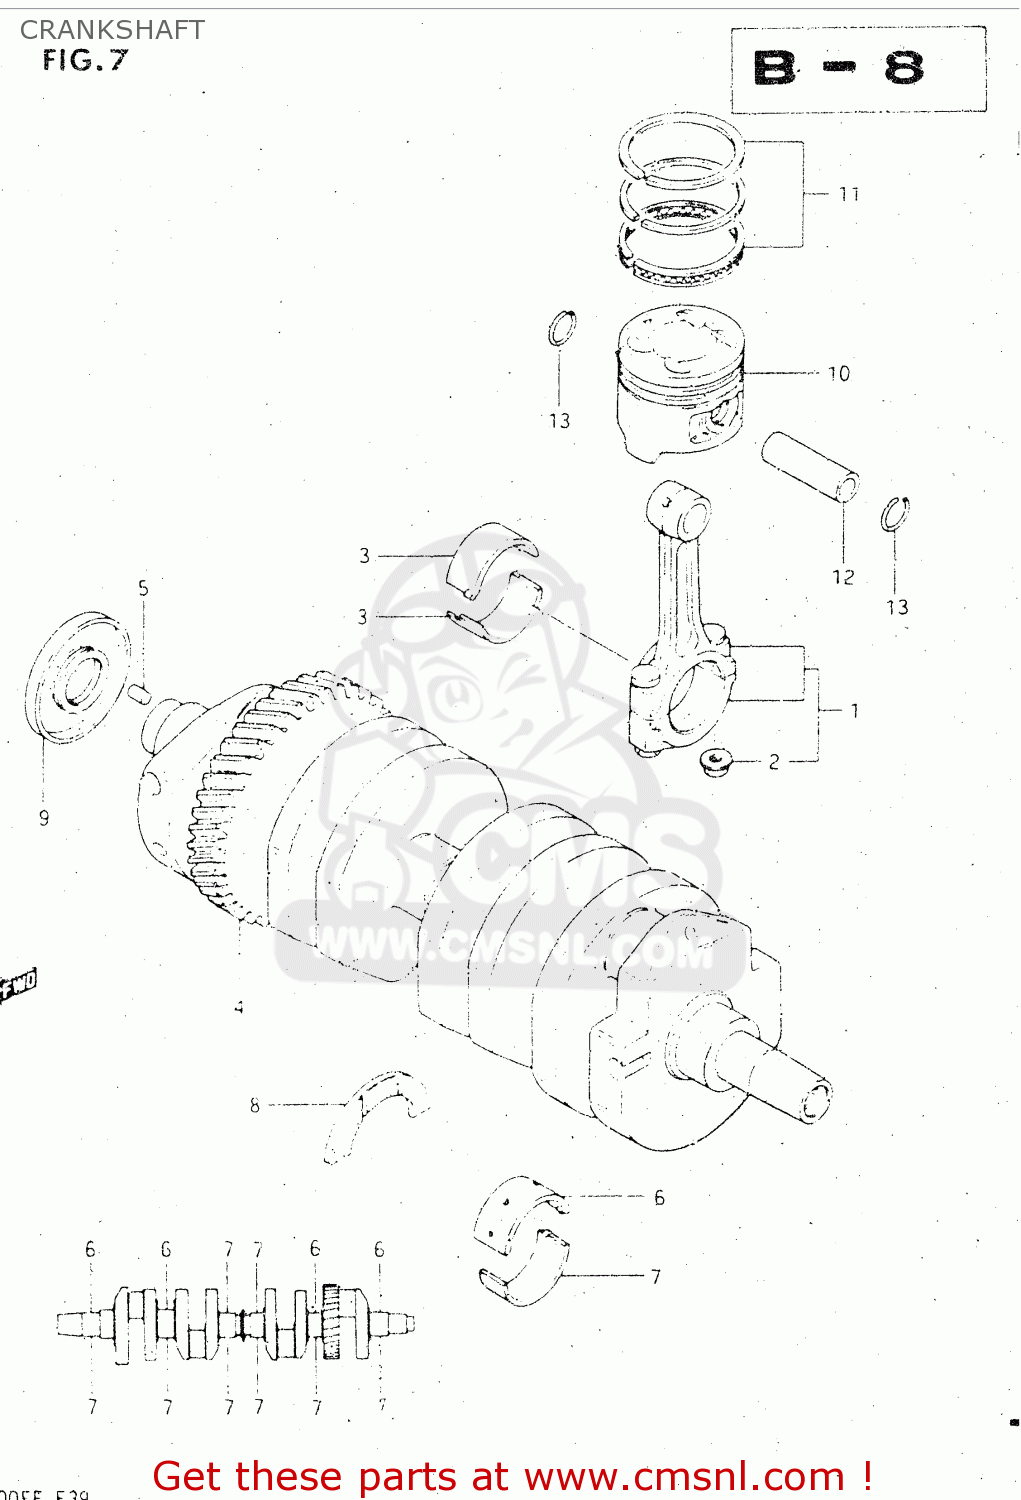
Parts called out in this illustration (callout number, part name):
1	ROD ASSY, CONNECTING
2	NUT
3	BEARING,CRANK PIN
4	CRANKSHAFT
5	PIN
6	BEARING,CRANKSHAFT
7	METAL CRANKSHAFT
8	PLATE,CRANK THRUST
9	OIL SEAL
10	PISTON (STD)
11	RING SET,PISTON
12	PIN,PISTON
13	CIRCLIP
